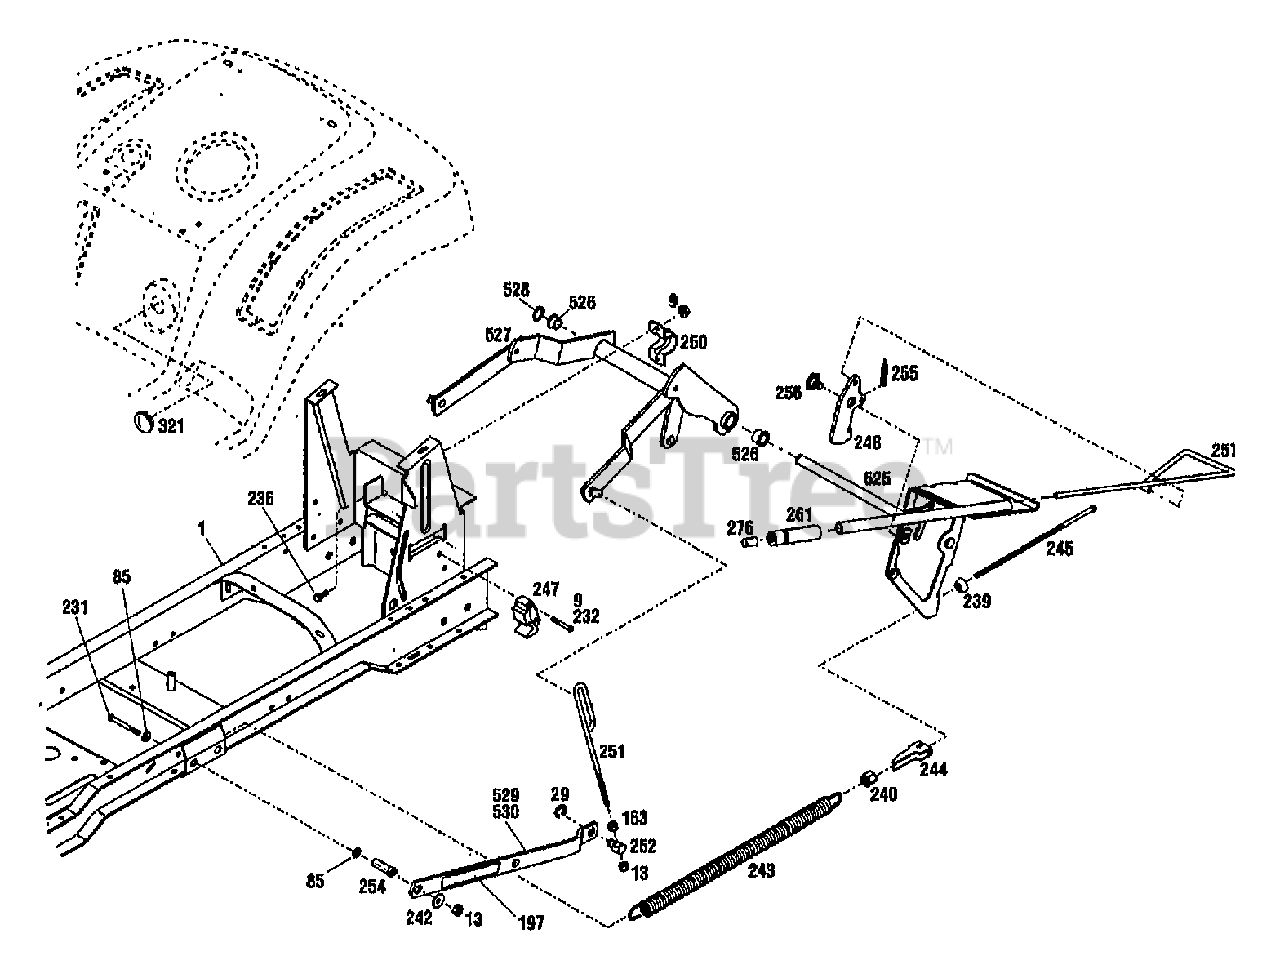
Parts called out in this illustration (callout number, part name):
1	ASSM-FRAME LTX
9	NUT-HFLK 5/16-18 ZP
13	NUT-LOCK 3/8-16
29	RING-RETAINING
85	WASHER-FLAT 3/8 SAE
163	NUT-HEX 3/8-16 ZP
197	DECAL-WARNING
231	SCR-HH 3/8-16X3.0 G5 ZP
232	SCR-HH 5/16-18X1.5 G5 ZP
236	SCR-HFLK 5/16-18X.75 ZP
239	BEARING-SPHERICAL
240	NUT-SPECIAL 5/16-18
242	WASHER-1.5X.375X.18 ZP
243	SPRING-LIFT ASSIST
244	BRKT-LIFT ASSIST
245	SCR-LIFT ASSIST
247	BLOCK-DETENT
250	CLAMP-LIFT
252	SWIVEL-REAR LIFT
254	SPACER
255	SPRING-EXTENSION
256	SCR-SHOULDER
261	GRIP-LIFT
276	BUTTON-LIFT
321	PLUG-DOME
525	HANDLE-LIFT
528	RING-RETAINING EXT .694 ID
529	LINK-LIFT W/DECAL
530	LINK-LIFT W/DECAL
